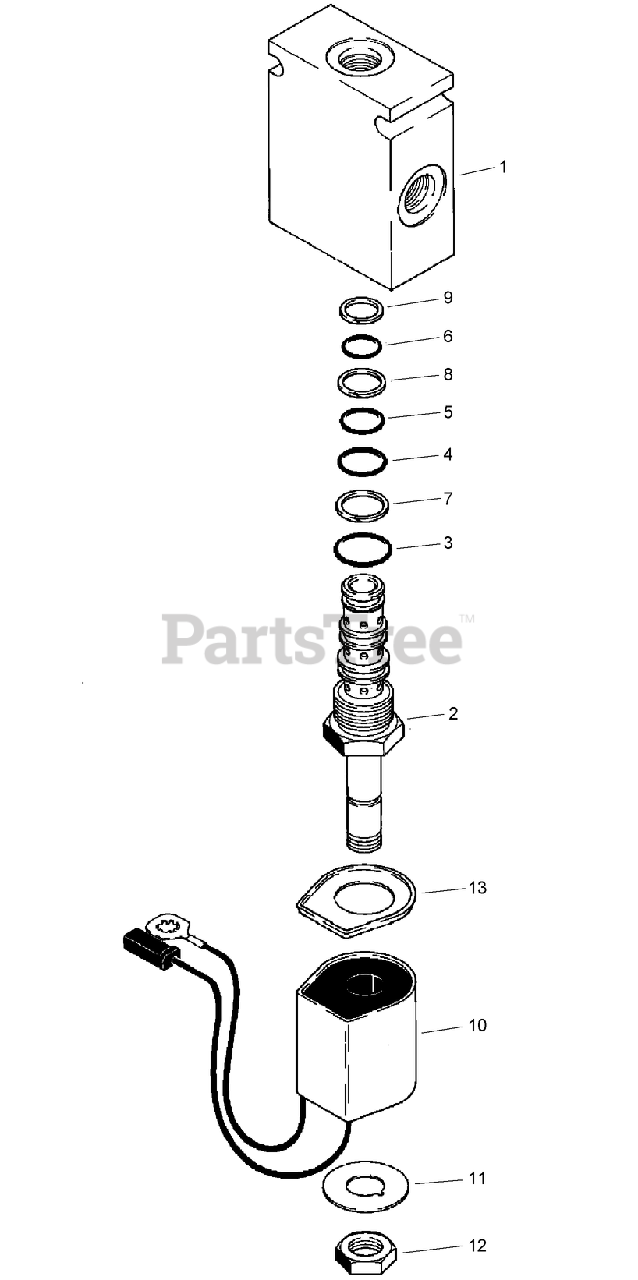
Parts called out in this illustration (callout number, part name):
1	BODY-valve
3	O-RING-valve
4	O-RING-valve
5	O-RING-valve
6	O-RING-valve
7	RING-backup, O-ring
8	RING-backup, O-ring
9	RING-backup, O-ring
10	HOUSING-with coil, valve
11	Plate-Coil
12	NUT-hex, housing
13	PLATE-cover, housing
